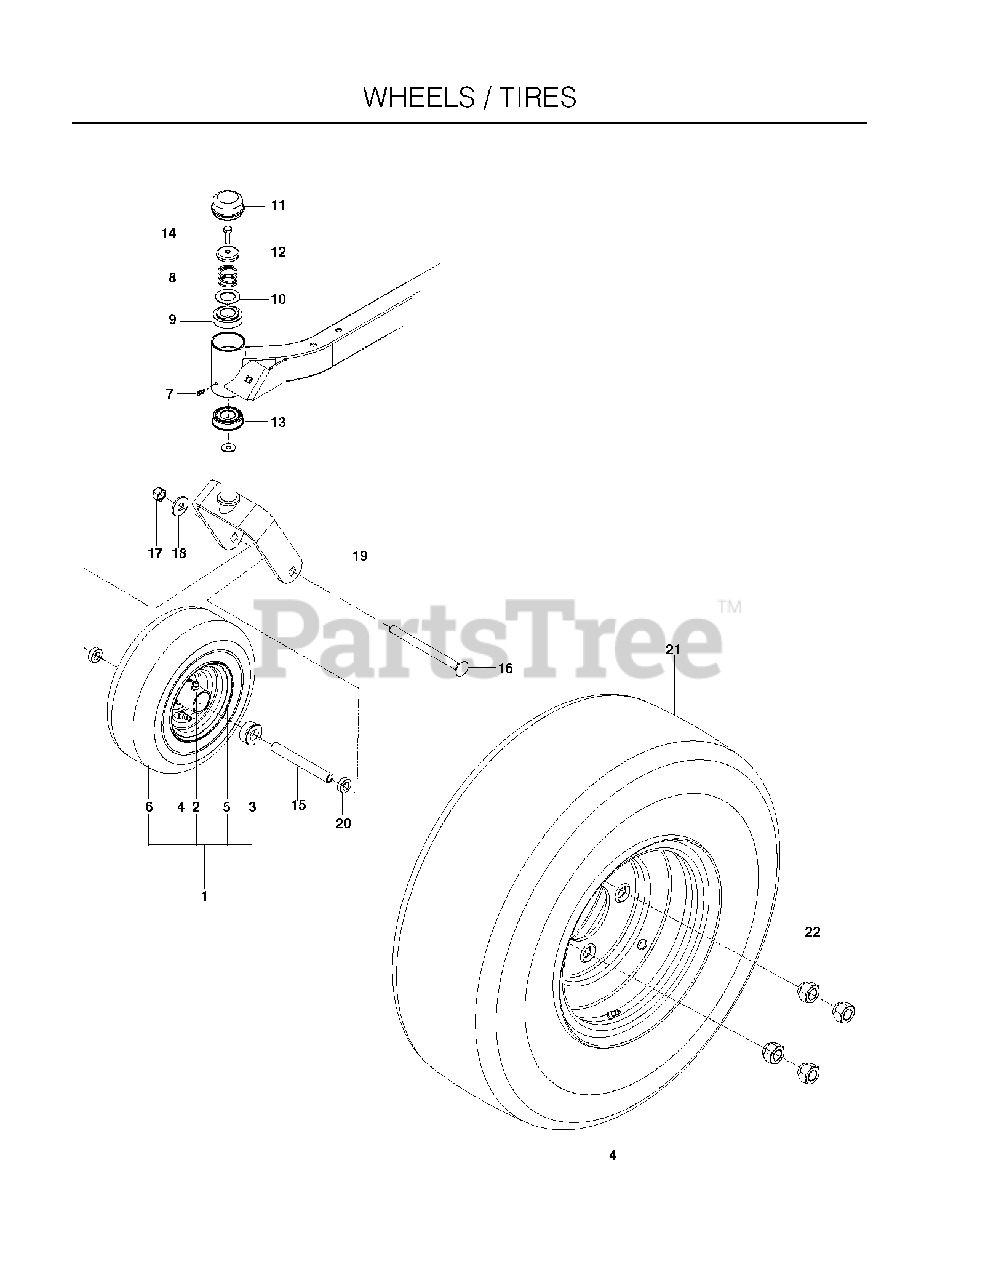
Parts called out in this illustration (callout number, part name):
1	TIRE.ASSEM.4.10-5.CASTER.GOLD
2	ZERK
3	BUSHING, WHEEL, 3/4"
4	VALVE STEM TR-412
6	TIRE.11"X4"-5.4PLY.SMOOTH.KEND
7	ZERK, 3/16, DRIVE IN
8	SPRING, CASTER
9	BUSHING, CASTER
10	WASHER, 1.025 ID X 1.64
11	GREASE CAP
12	CASTER.PLUG
13	BEARING FLANGED
14	5/16-18X1 HHB G5W/NY
16	RHSNB 1/2-13 X 6.50 GR2 ZD
17	NUT 1/2-13 HEX CNTRLK GR 5 ZD
18	WASH USS FLAT 1/2
19	YOKE.CASTER.ORANGE
20	SPACER, 5/16"
21	REAR.WHEEL.TIRE.18X6.5X8.KENDA
22	LUG NUT 1/2F
